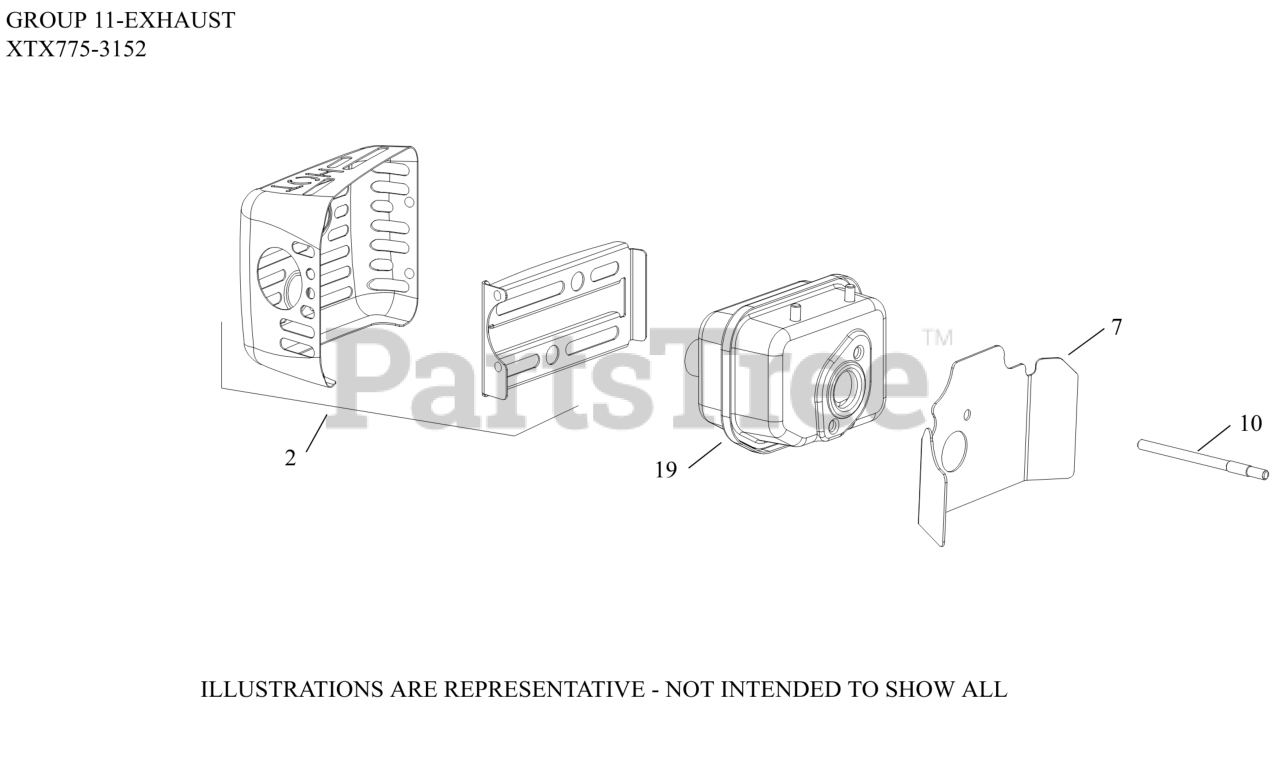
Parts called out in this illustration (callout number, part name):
2	GUARD, MUFFLER
7	GASKET, MUFFLER (HEAT DEFLECTOR)
10	STUD (M6)
19	MUFFLER ASSEMBLY
